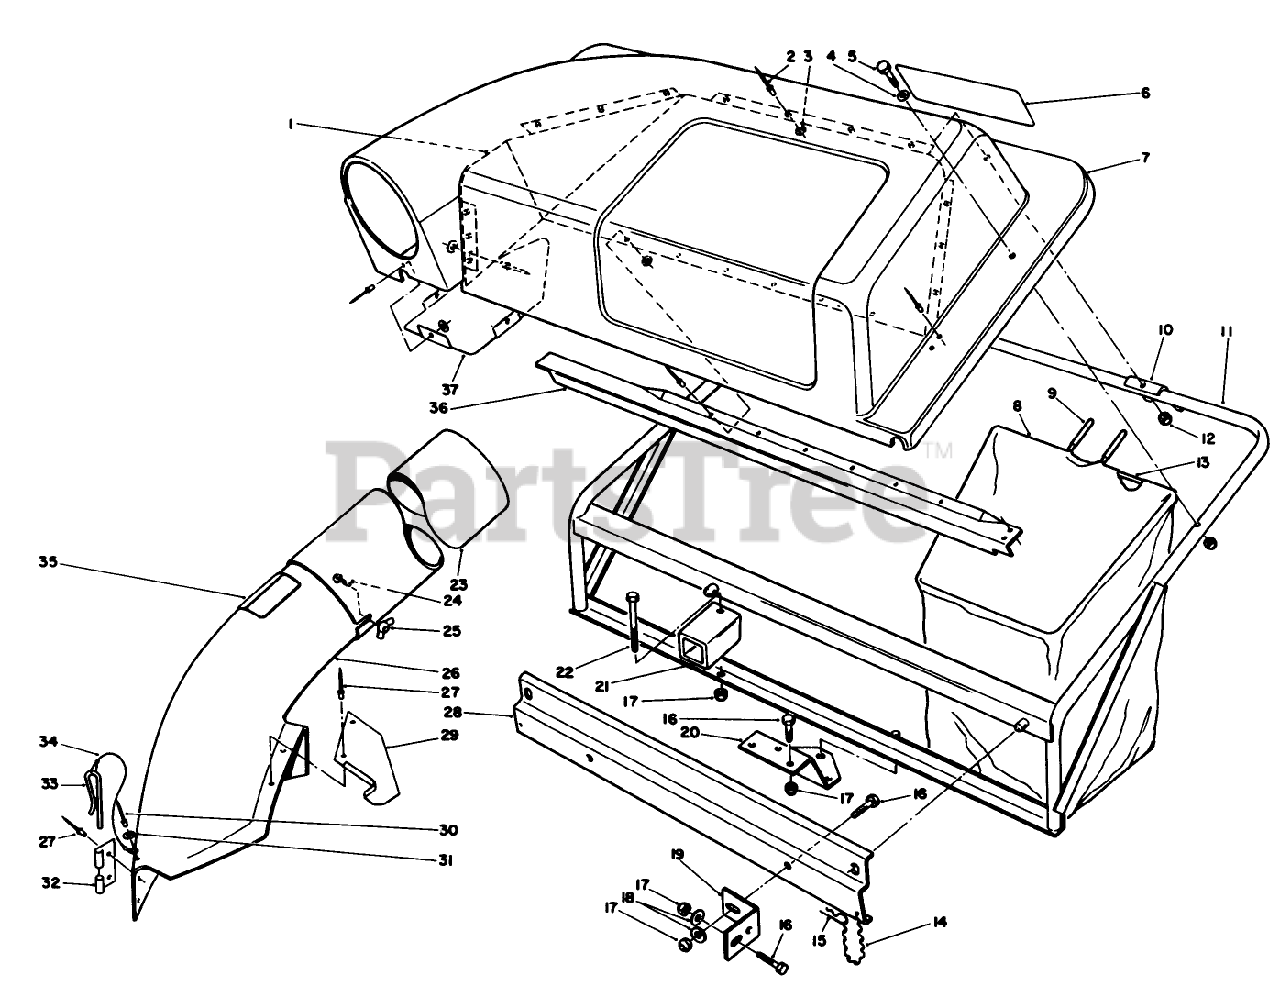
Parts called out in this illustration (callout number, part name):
2	RIVET-POP
3	WASHER-FLAT
4	WASHER-PLAIN
5	SCREW-HH
9	GRIP-HANDLE, BAG
12	NUT-ACORN
15	PIN-HAIR
16	SCREW-HH
17	NUT-LOCK, NI
18	WASHER-PLAIN
20	MTG PLATE *B
22	SCREW-HH
24	BOLT-CARR
25	NUT-WING SPECL
26	CHUTE ASM
27	RIVET-BLIND
29	CHUTE SUPT BRKT
30	RIVET-BLIND
31	WASHER-PLAIN
32	BRACKET-MOUNTING, CHUTE
33	PIN-LOCKING, CHUTE
34	LANYARD
